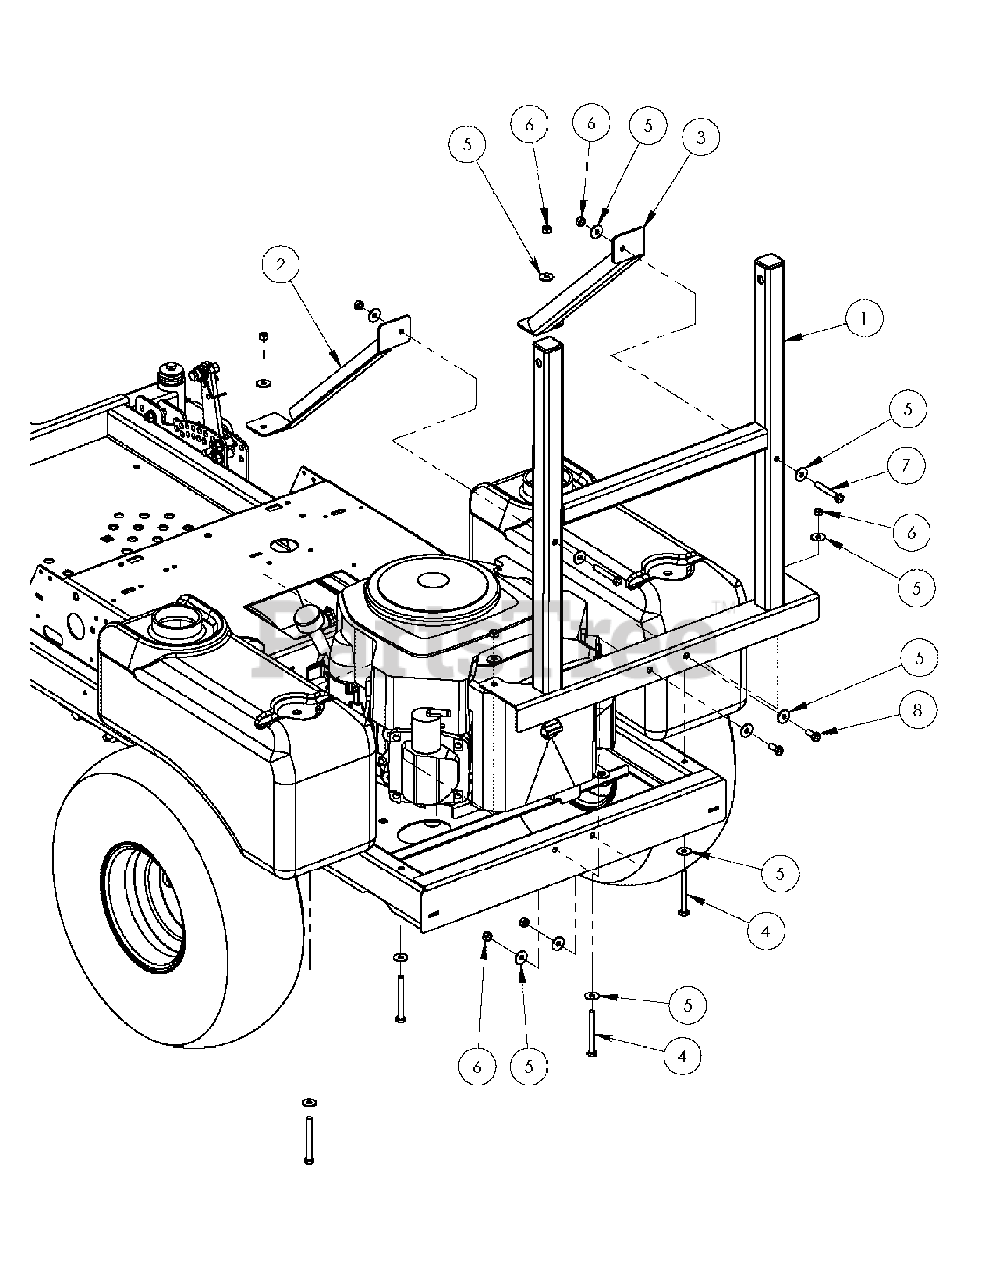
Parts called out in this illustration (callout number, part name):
1	CATCHER MOUNT
2	LEFT LEG BRACE
3	RIGHT LEG BRACE
4	CAP SCREW, 5/16"-18 X 3" LONG
5	FLAT WASHER-5/16"
6	HEX NUT, NYLON INSERT 5/16"
7	CAP SCREW, 5/16"-18 X 2 1/2" LONG
8	CAP SCREW, 5/16"-18 X 3/4" LONG
